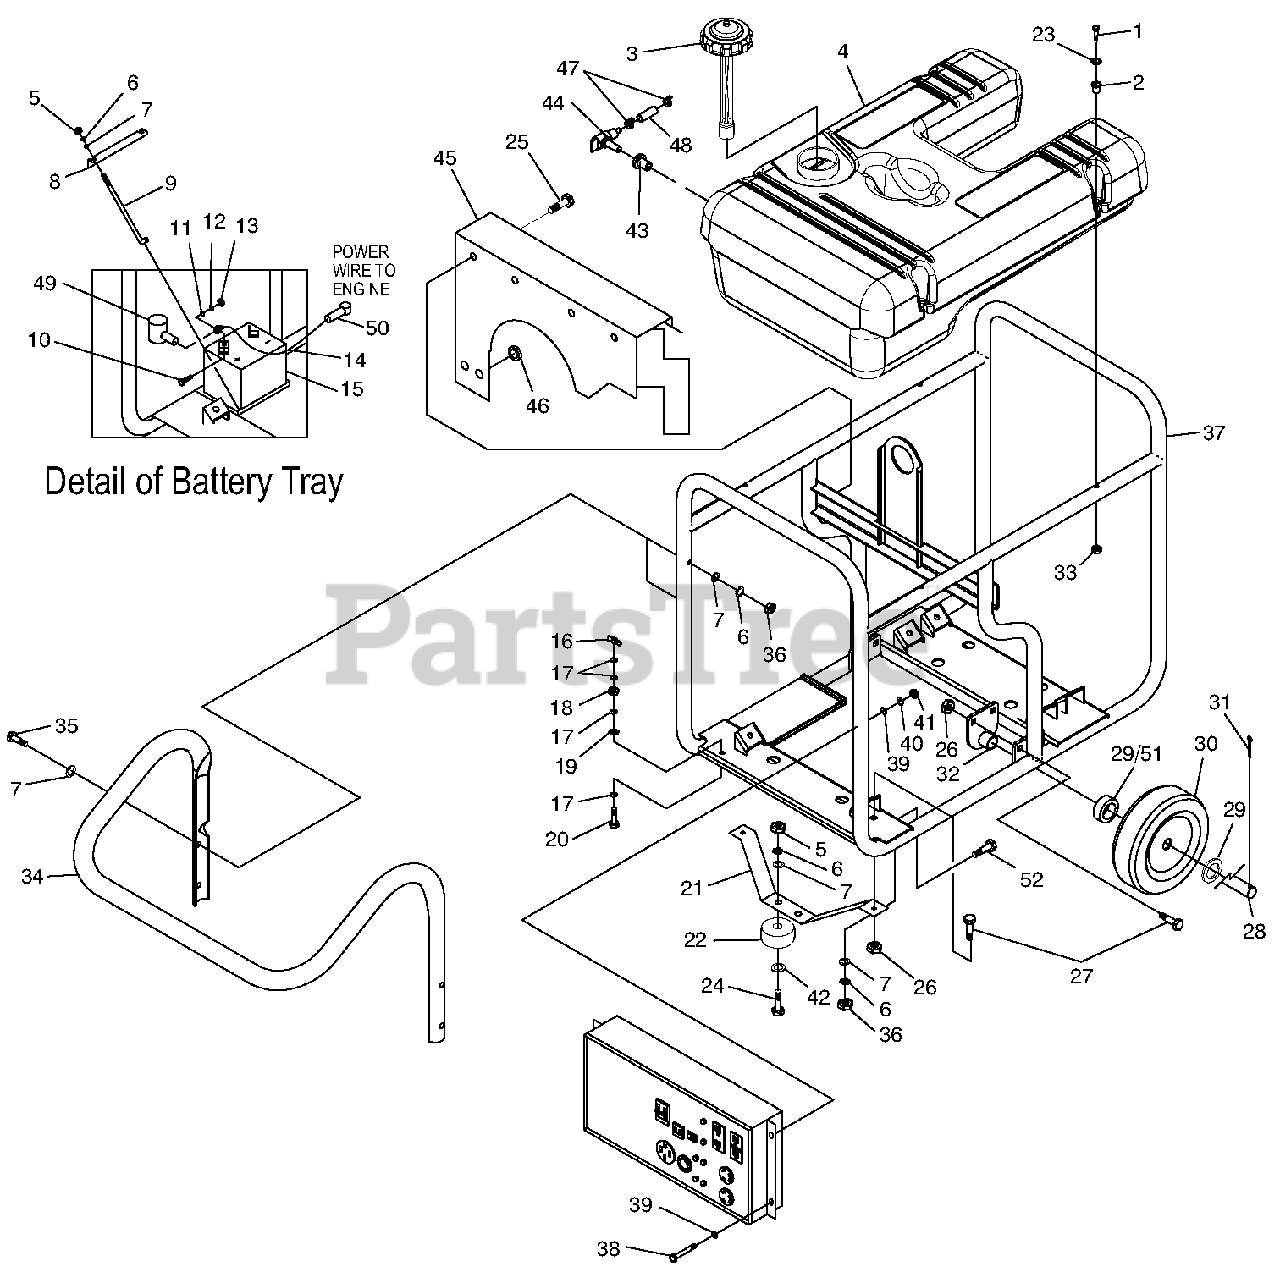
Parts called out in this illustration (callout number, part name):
1	SCREW HHC M6-1.0 X 55
2	RUBBER TANK MOUNT
3	CAP, FUEL WITH GAUGE & VENT
4	KIT, FUEL TANK
5	NUT HEX M8-1.25
6	WASHER LOCK M8-5/16
7	WASHER FLAT 5/16
8	BRACKET BATTERY
9	BOLT,BATTERY J-BOLT
10	SCREW HHC 1/4-20 X 3/4 G5
11	WASHER FLAT 1/4
12	WASHER LOCK M6-1/4
13	NUT HEX 1/4-20
14	BATTERY CABLE, RED
15	BATTERY U1
16	NUT WING 5/16-18 BRASS
17	WASHER FLAT 5/16 BRASS
18	NUT HEX 5/16-18 BRASS
19	5/16 SPECIAL L/WASH
20	SCREW HHC 5/16-18 X 1.5 BRASS
21	BRACKET FRONT FOOT (15 kW)
22	VIB MOUNT
23	WASHER FLAT .25ID X 1"OD
24	SCREW HHC M8-1.25 X 30
25	SCREW HHTT M6-1.0 X 12
26	NUT LOCK FL 3/8-16
27	BOLT CARR 3/8-16 X 1
28	AXLE, 3/4"DIA X 30" (15 kW)
29	WASHER FLAT 3/4" (15 kW)
30	12.3" PNEUM WHEEL 3/4" AXLE (15 kW)
31	PIN COTTER 1/8 X 1-1/4
32	BRACKET, WHEEL SPACER
33	NUT FLANGE M6-1.0 NYLOK
35	SCREW HHC 5/16-18 X 2-1/2 G5
36	NUT LOCK HEX 5/16-18 NYLON INSERT
37	FRAME
38	SCREW HHC M5-0.8 X 45 G8.8
39	WASHER FLAT M5
40	WASHER LOCK M5
41	NUT HEX M5-0.8
42	WASHER FLAT 1"
43	BUSHING TANK DEXTOR
44	VALVE, PLASTIC TANK
45	AIR DEFLECTOR
46	GROMMET .75 X .06 X .50
47	CLAMP HOSE BAND 1/4
48	HOSE 1/4 ID
49	BOOT BATTERY CABLE
50	BOOT STARTER CABLE
51	SPACER, AXLE (15 kW)
52	SCREW HHC 5/16"-18 X 1"
